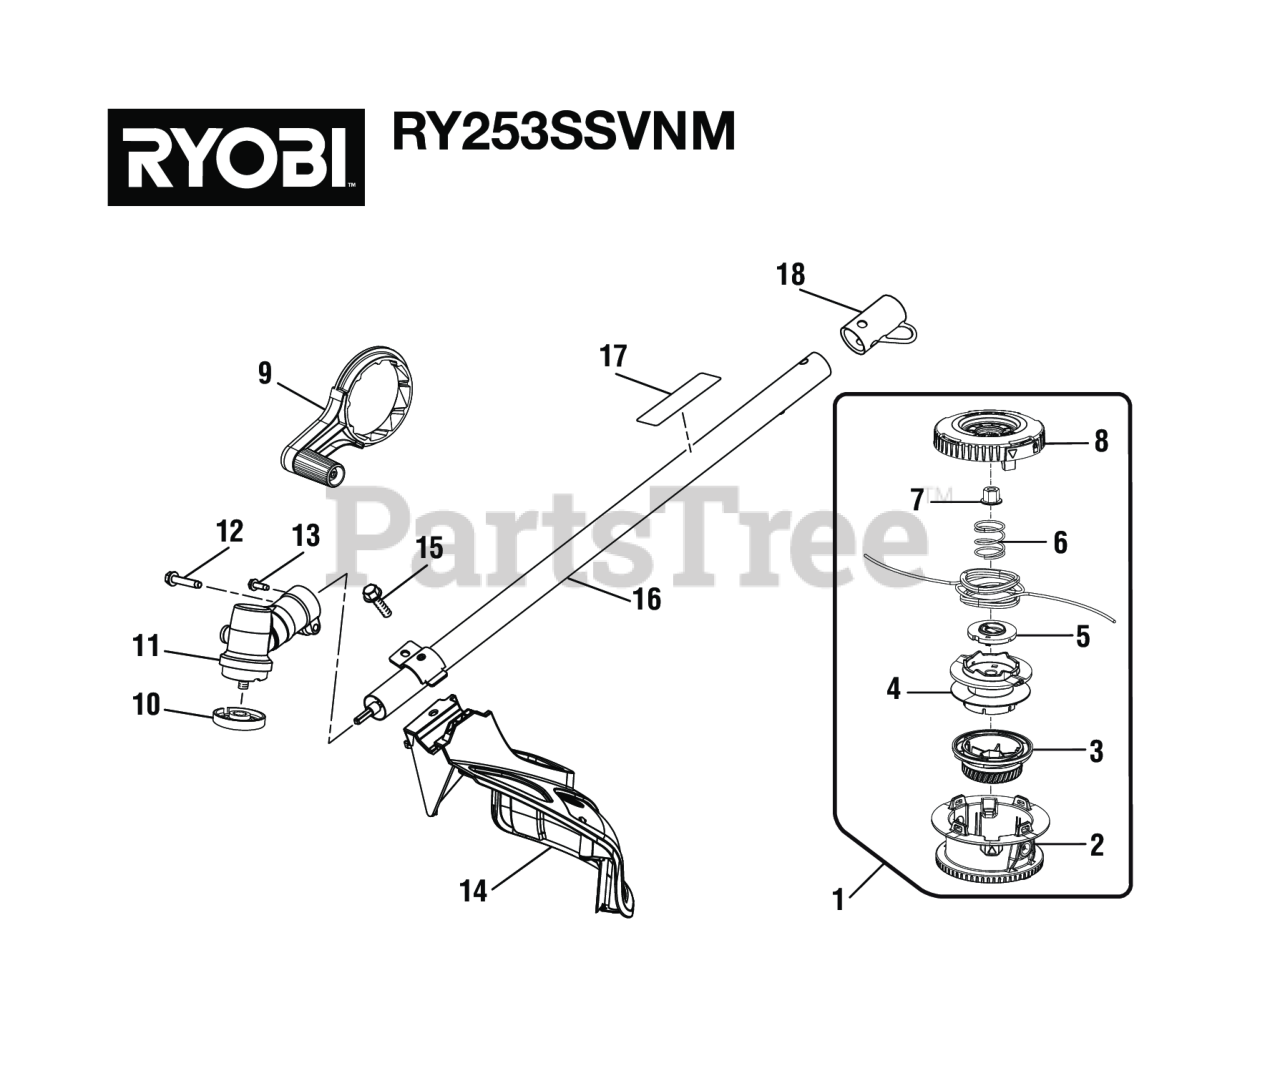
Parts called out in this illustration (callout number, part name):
1	Trimmer Head Assembly (.095) (Inc. Key Nos. 19-25)
2	Bump Head
3	Bump Knob (Green)
4	Spool Assembly
5	String Guide
6	Compression Spring
7	Hex Nut (M8, Left Hand Threads)
8	Locking Assembly
9	Crank Handle
10	FLANGED WASHER
11	Gear Case Assembly
12	Screw (1/4-20 x 1-1/4 in., Hex Washer Hd. S.T.)
13	Screw w/Washer (10-24 x 5/8 in., Hex Hd. T.F.)
14	Grass Deflector Assembly
15	SCREW (#1/4-20 X 1-1/4 in. HEX WASHER HD.)
16	Straight Shaft Assembly (Inc. Key Nos. 17-18)
17	Warning Icon Label
18	Storage Hanger Cap
